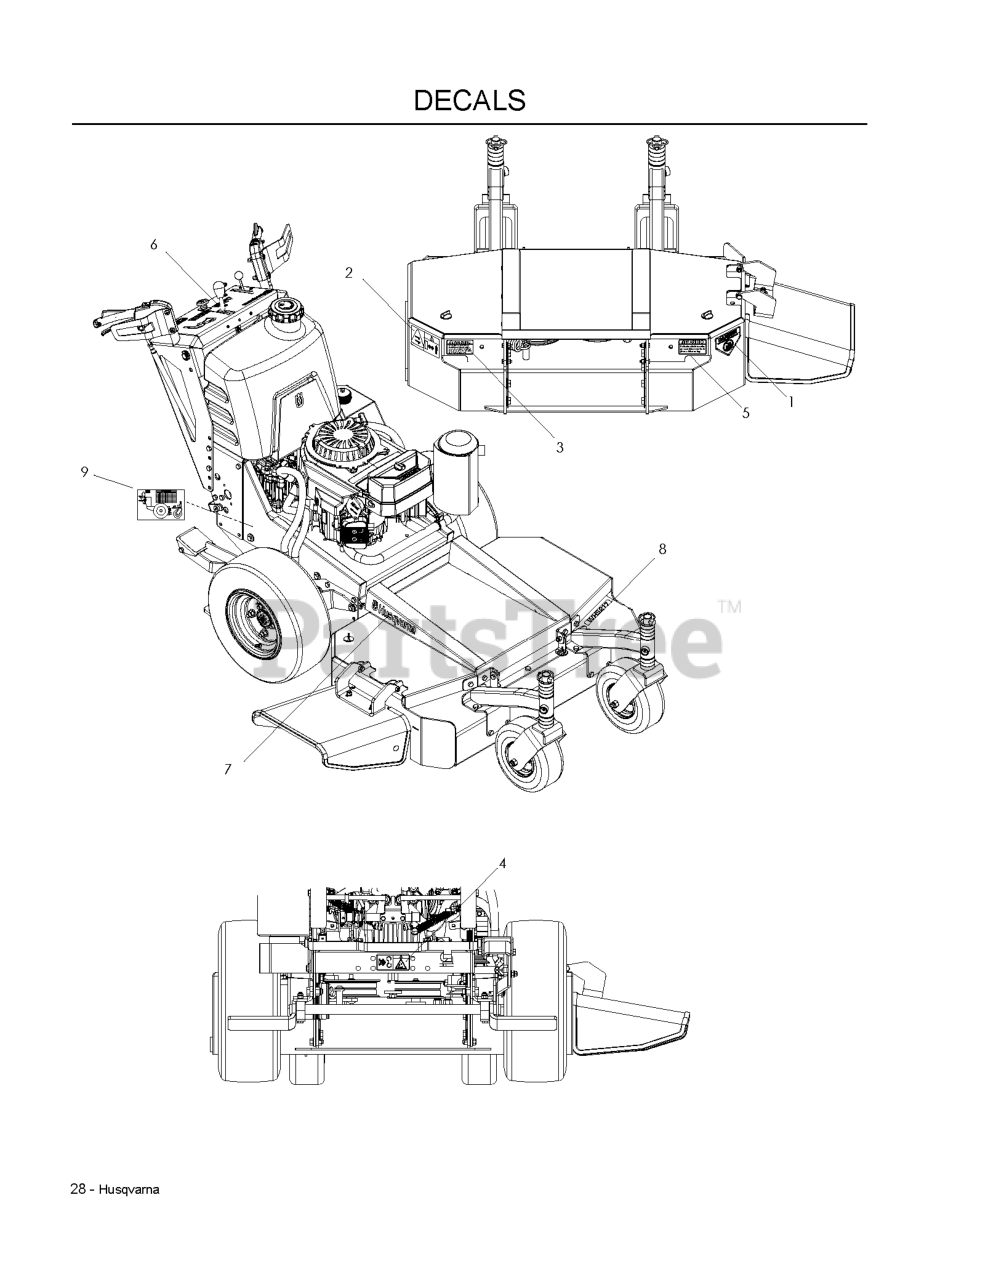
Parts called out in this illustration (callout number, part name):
1	DECAL, CPSC
2	DECAL, EURO SEVERING
3	DECAL, PROP. 65
4	DECAL, BELT DRIVE
5	DECAL, CAUTION
6	DECAL, INST PANEL
7	DECAL.HOOD.LOGO.ORANGE.HUSQVAR
8	DECAL, CROWN H 70MM
9	DECAL, HEIGHT OF CUT
